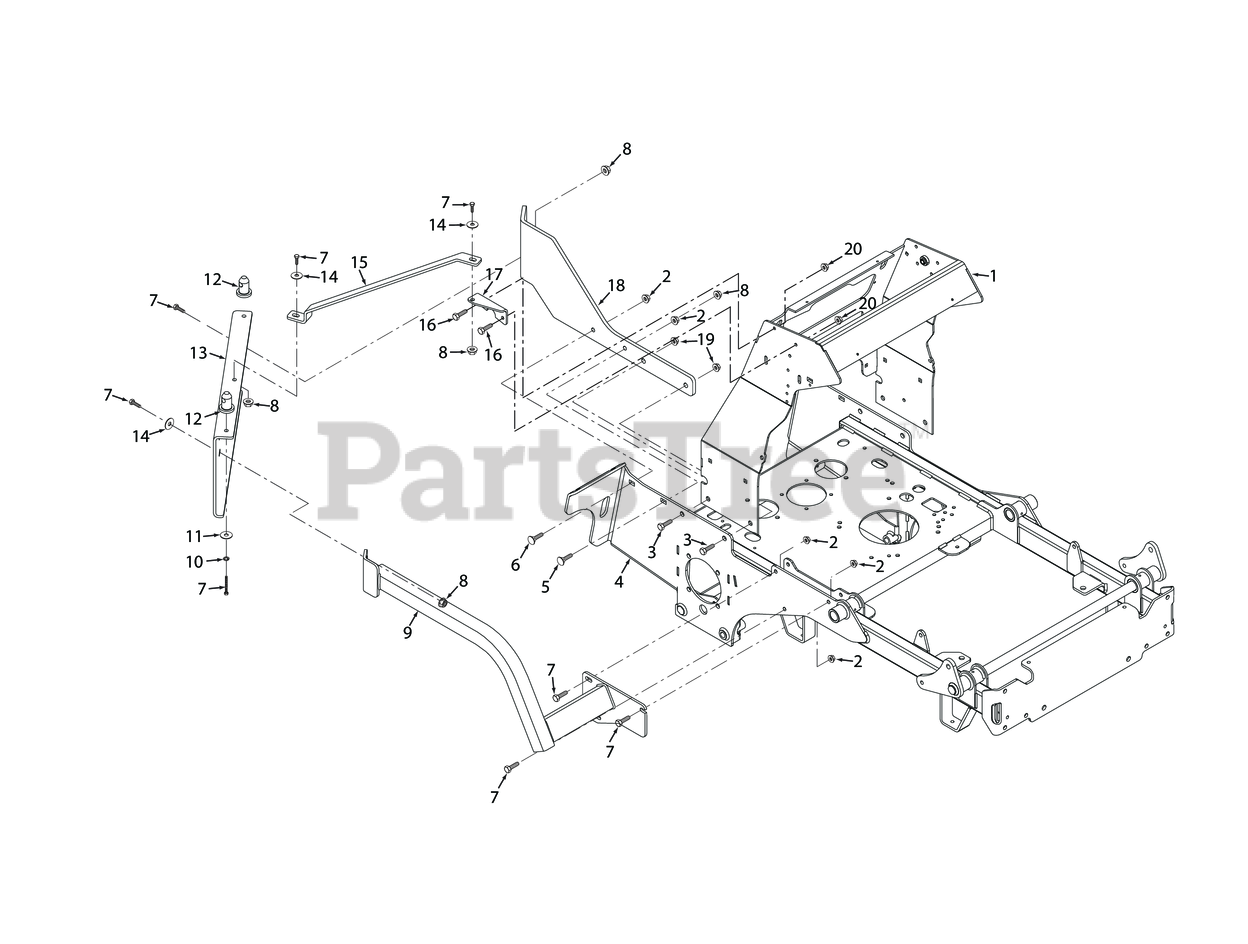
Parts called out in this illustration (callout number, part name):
1	Handlebar Weldment, SVRII
2	NUT, 3/8-16 SERRATED FLANGE HEX HEAD
3	Serr. Fl. Hex Head CPSCR, 1/2-13 x 2.00"
4	Mainframe Weldment, SVRII
5	SHORT SQUARE NECK CARRIAGE BOLT, 3/8-16 X 2"
6	Carriage Bolt, 3/8-16 x 1-1/4"
7	Bolt, Hex Head 3/8-16 x 1-1/4", Kawasaki FX / FS
8	Nut, Flange Elastic Stop Nut, 3/8-16
9	Bracket Weldment, GC Mounting
10	Lockwasher, 3/8" Spring, Kawasaki FX / FS
11	Flatwasher, 3/8-.406 x 1-1-1/2 x 7 Gauge
12	Pin, GC Locator
13	Bag Support Plate
14	Flatwasher, 3/8" Special (.391 x .938 x .105)
15	Upper Support Bracket
16	Bolt, Heax Head 5/16-18 x 1" (48V / 52V)
17	Mounting Bracket, Upper
18	GC Mounting Bracket, LH
19	Nut, Hex Serrated Flange 1/2-13
20	Nut, Serrated Flange 5/16-18 (Right Front Engine Mounting, Briggs and Kohler Only)
